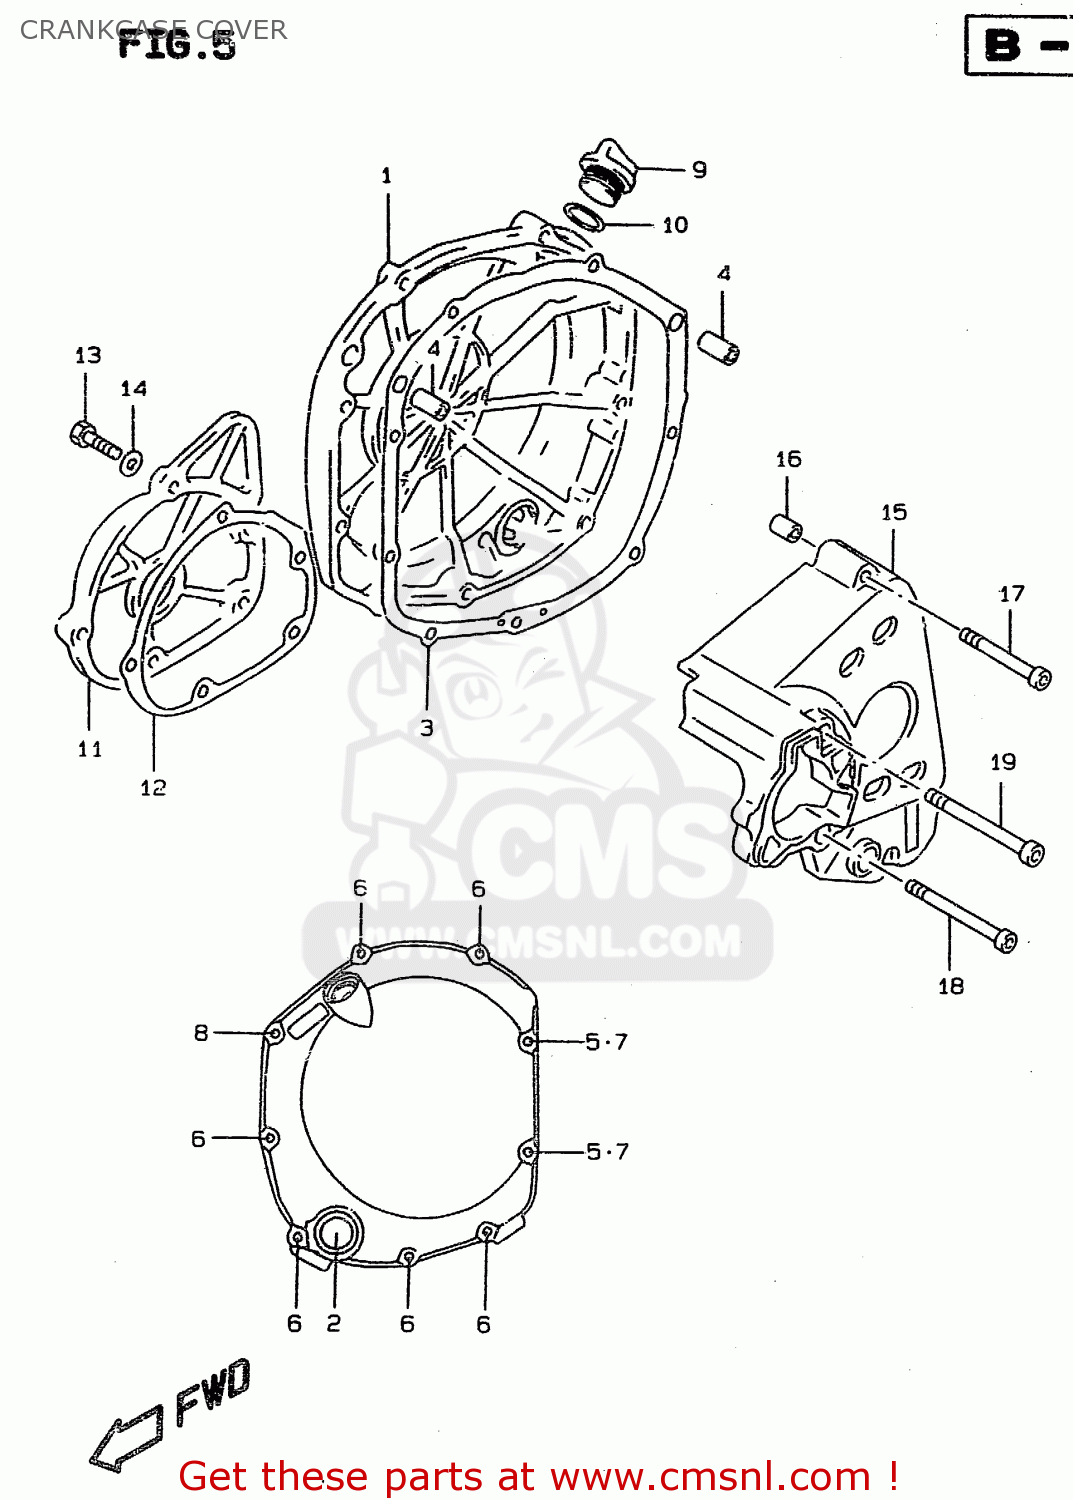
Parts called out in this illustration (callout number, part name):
1	COVER,CLUTCH
2	LENS,OIL LEVEL CHECK
3	GASKET,CL COVER (NAS)
4	PIN
5	GASKET(5.8X11X1.2) (NAS)
6	BOLT,CL.COVER
7	BOLT
8	BOLT
9	PLUG
10	O RING(D:3.1,ID:16.8)
11	COVER,SIGNAL GENERATOR
12	GASKET,SIGNAL GEN COVER
13	BOLT(6X22)
14	GASKET(5.8X11X1.2) (NAS)
15	COVER,ENGINE SPROCKET
16	PIN
17	BOLT,CL.COVER
18	BOLT
19	BOLT
